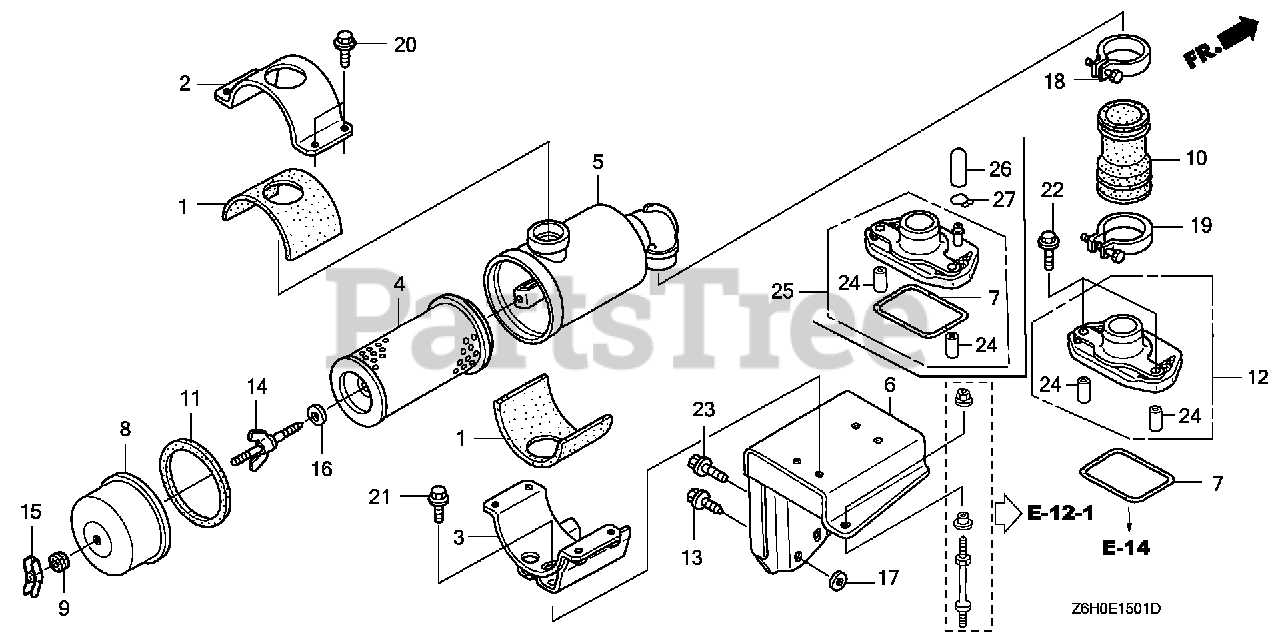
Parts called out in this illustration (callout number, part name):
1	RUBBER, AIR CLEANER HOLDER (UPPER)
2	HOLDER, AIR CLEANER (UPPER)
3	HOLDER, AIR CLEANER (LOWER)
4	ELEMENT, AIR CLEANER
5	HOUSING, AIR CLEANER
6	STAY, AIR CLEANER
7	SEAL, AIR CLEANER HOUSING
8	COVER, AIR CLEANER
9	GROMMET, AIR CLEANER
10	TUBE, AIR CLEANER CONNECTING
11	SEAL, AIR CLEANER
12	JOINT B, CONNECTING TUBE
13	BOLT, FLANGE (6X18) (CT200)
14	BOLT, AIR CLEANER
15	WINGNUT (6MM) (BLACK)
16	WASHER, AIR CLEANER
17	COLLAR, SEAT
18	BAND, AIR CLEANER CONNECTING TUBE (52)
19	BAND, AIR CLEANER CONNECTING TUBE (58)
20	BOLT, FLANGE (6X12)
21	BOLT, FLANGE (6X16)
22	BOLT, FLANGE (6X28)
23	BOLT, FLANGE (8X16)
24	COLLAR A, AIR CLEANER
25	JOINT B, CONNECTING TUBE
